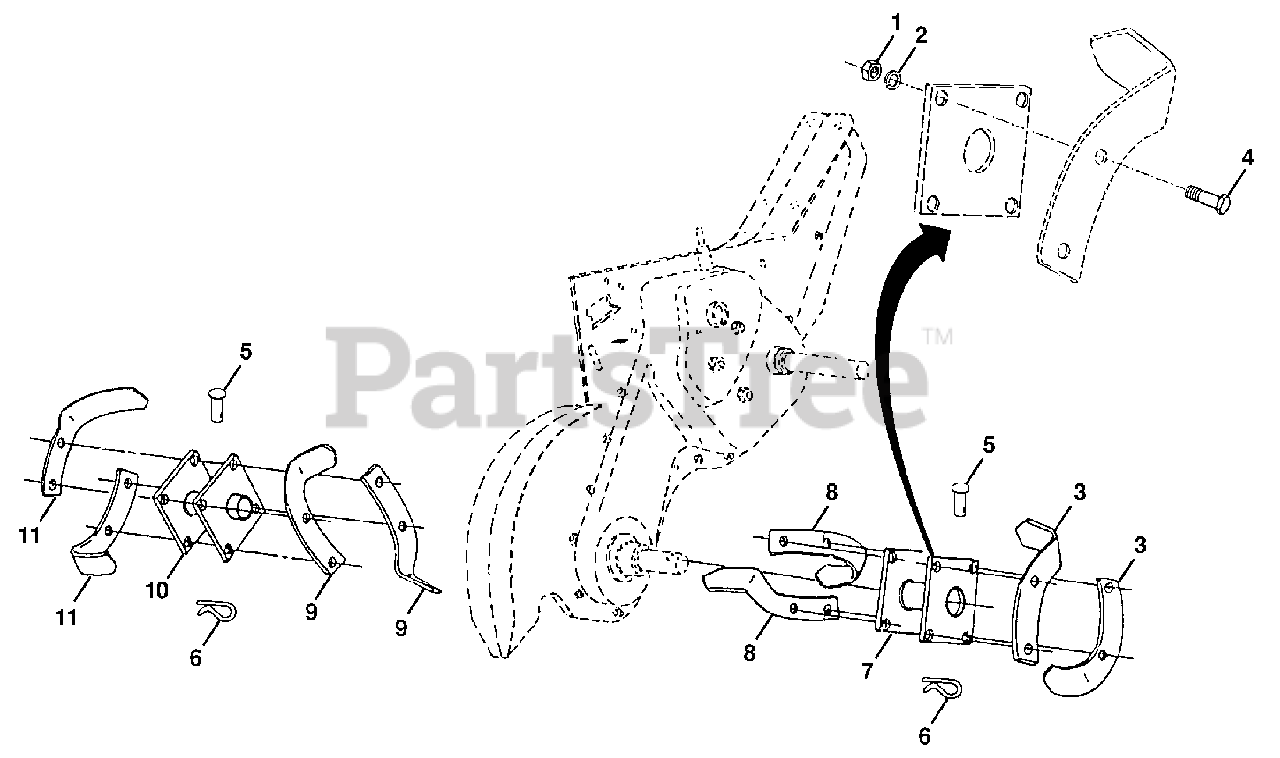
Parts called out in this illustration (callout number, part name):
1	Nut, Hex 3/8-24
2	Washer, Lock 3/8
3	Tine, Outer, R.H.
4	Bolt, Hex 3/8-24 x 1
5	Pin, Shear
6	Clip, Hairpin
7	Assembly, Hub and Plate, R.H.
8	Tine, Inner, R.H.
9	Tine, Inner, L.H.
10	Assembly, Hub and Plate, L.H.
11	Tine, Outer, L.H.
